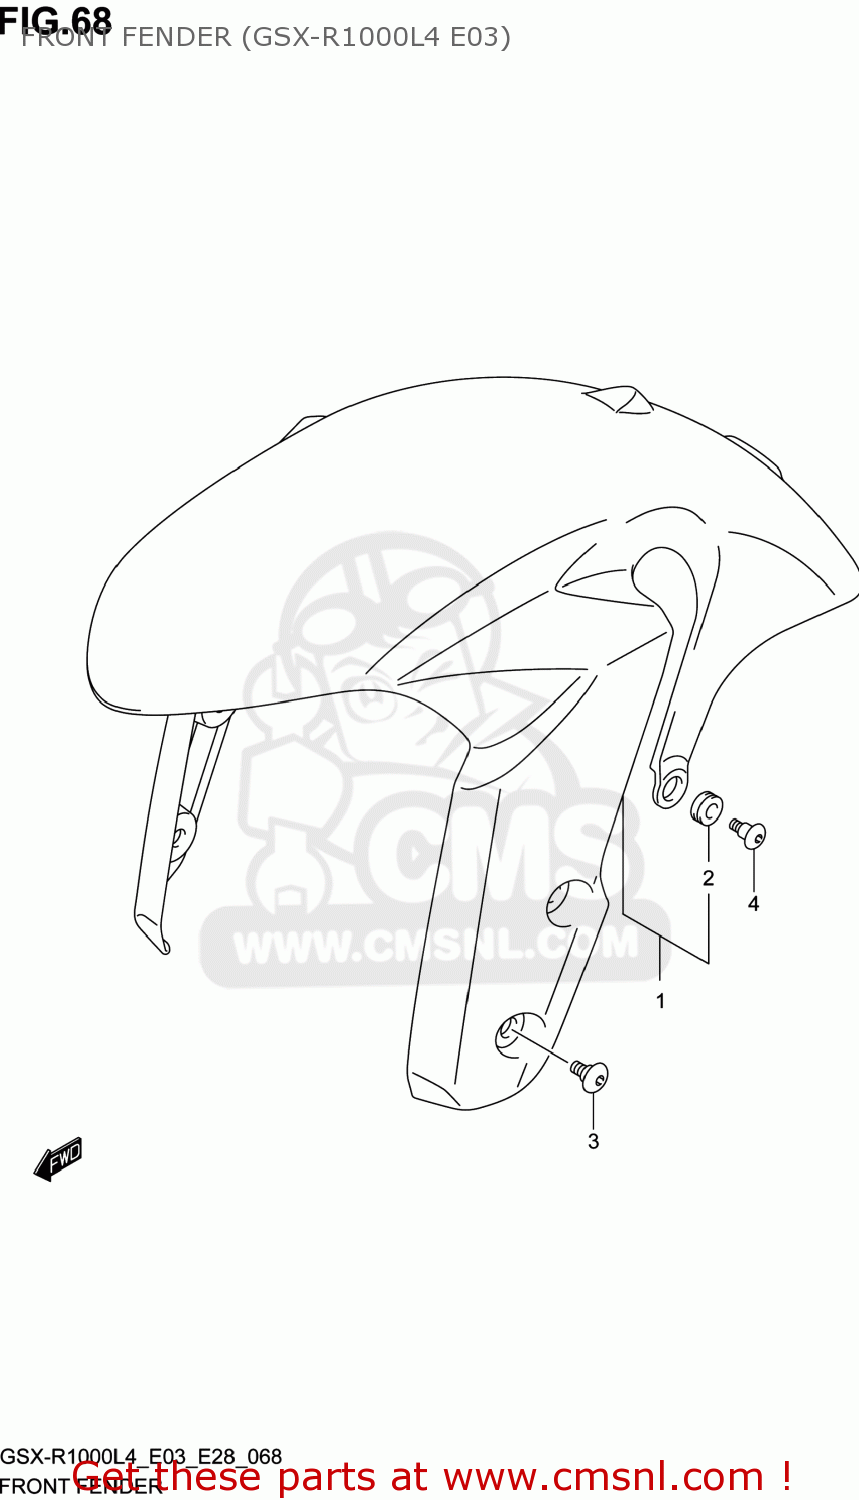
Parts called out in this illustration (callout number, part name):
1	FENDER ASSY,FR(BLACK)
2	CUSHION
3	SCREW(6X16)
4	SCREW(6X16)
